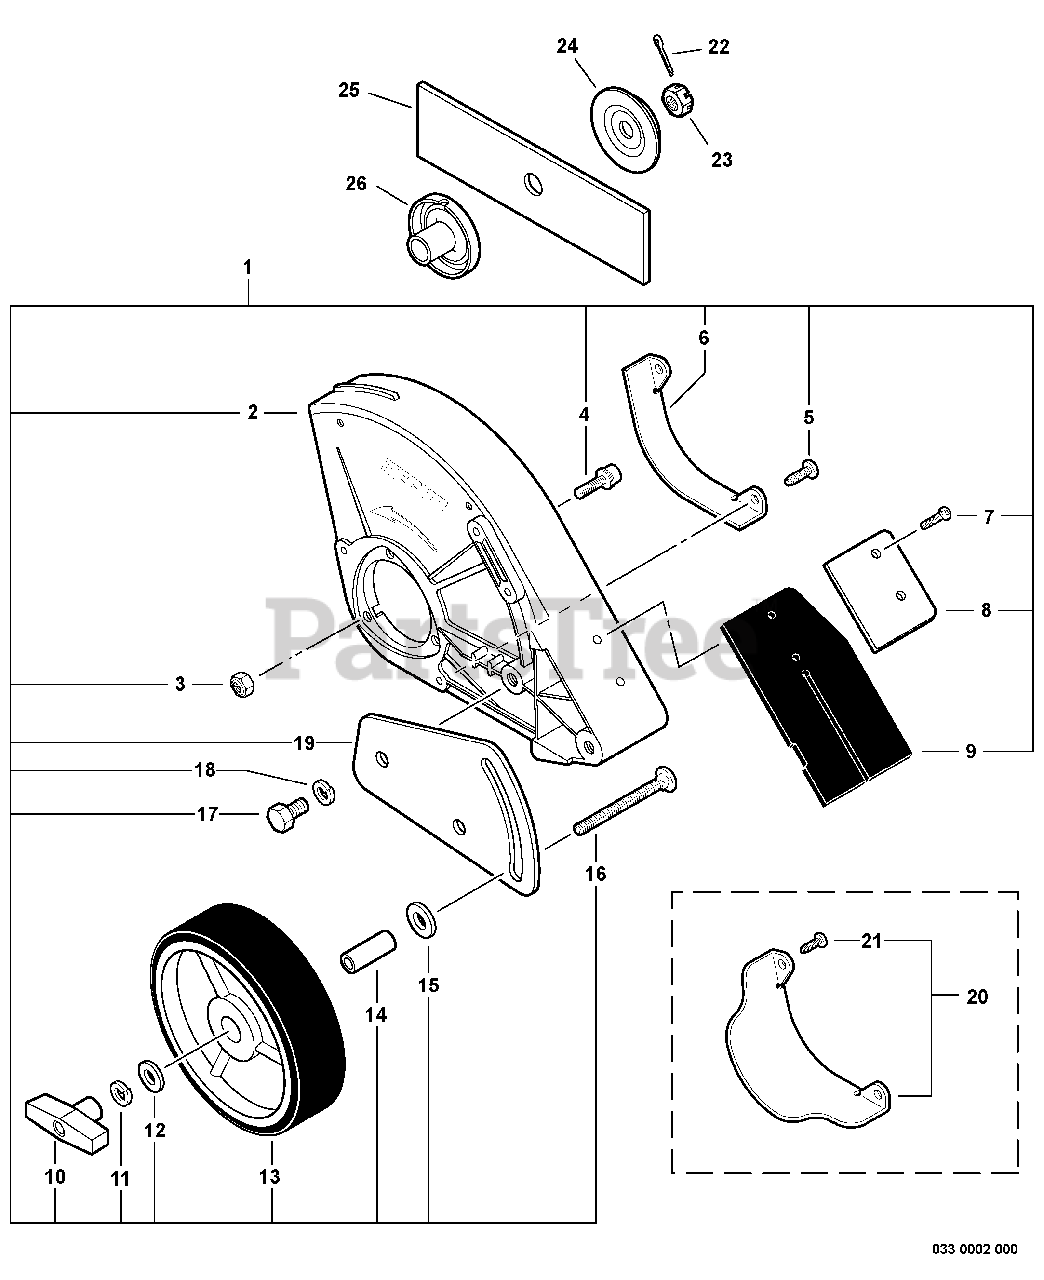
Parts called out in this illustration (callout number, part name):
1	SHIELD KIT
2	SHIELD, DEBRIS
3	NUT, LOCK M5
4	BOLT 5×25
5	SCREW 4×12
6	GUARD, SHIELD
7	SCREW 4×12
8	PLATE, FLAP
9	FLAP, DEBRIS
10	KNOB, FASTENER
11	WASHER, SPRING 8
13	WHEEL
14	COLLAR 12
15	WASHER, SPRING 10
16	BOLT 5/16"-18×2-1/2"
17	BOLT 8×14
18	WASHER, SPRING 8
19	BRACKET, WHEEL
20	GUARD KIT, SHIELD
21	SCREW 4×12
22	PIN, COTTER 2×22
23	NUT 10×1.25 LH
24	PLATE, ADAPTOR - LOWER
25	BLADE - 2 PK
26	PLATE, ADAPTOR - UPPER
